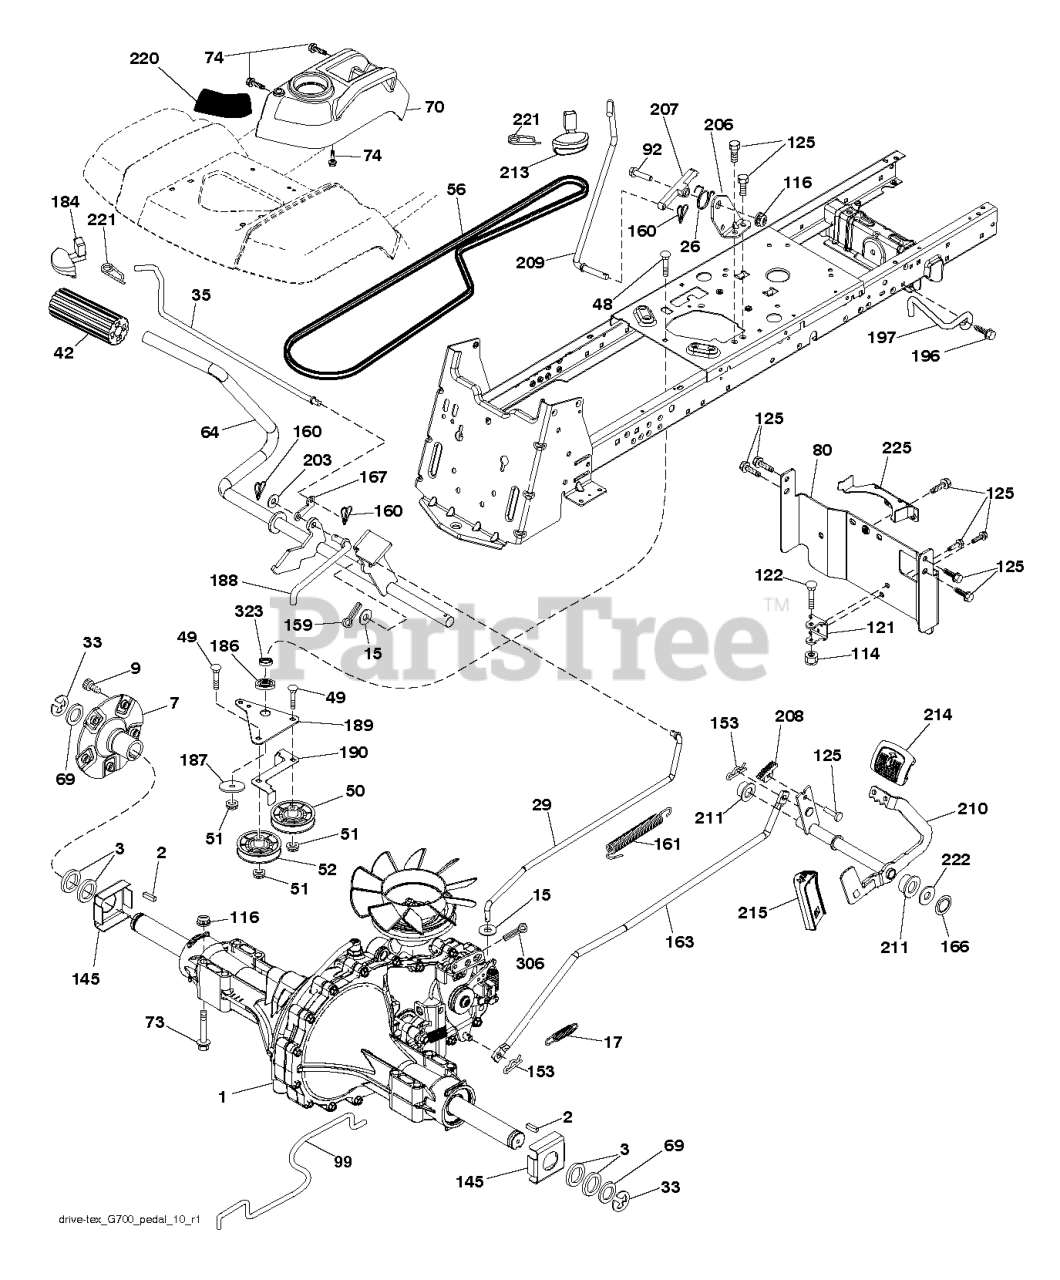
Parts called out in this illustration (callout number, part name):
2	KEY 1/4 X 2.5
7	HUB.ASM.WHEEL.REAR.23"TEX
9	HUB BOLT
15	WASHER
17	SPRING.BRAKE.K46
26	SPRING.RETURN.CRUISE
29	ROD.BRAKE.K66
33	E RING HYT
35	ROD .BRAKE. PARKING. GT. HUSQ.
42	PEDAL COVER T
48	BOLT.3/8-16X1.50
50	IDLER.FLAT.910.OFFSET
51	NUT LOCK FLG 3/8-16 UNC
52	IDLER.V-GROOVE.910.OFFSET
64	SHAFT.ASM.PEDAL.BRK.CNTR
70	CONSOLE.ASM.RH.GT.FC.HUSQ
73	BOLT HEX 5/16-18 GR 5
74	SCREW.HI-LO.CONSOLE
80	STRAP.TORQUE.K66
92	BOLT
99	ROD.SPRING.BYPASS.K66.GT.Z
114	NUT.71038.31-18.HEX.NYLOCK
116	NUT LOCK HEX FLANGE 5/16-18
121	BRACKET STRAP TORQUE
122	BOLT.5/16-18X2.5
125	SCREW
145	WASHER.AXLE.FLANGE.HG-3000
153	RETAINER M
159	COTTER PIN
160	RETAINER CLIP
161	SPRING, RETURN LT
163	ROD.PEDAL.CONTROL
166	NUT.PUSH.625
167	LATCH.BRAKE.SPRING
184	RB HANDLE.PARKG.BRK.HUS/PRED
186	BOLT.5/16-18X2.5
187	WASHER 12/32X2X10GA
188	RP.LINK.CLUTCH.GROUND.DRIVE
189	BELLCRANK.GROUND.DRIVE.TEX.
190	KEEPER.BELLCRANK.DRIVE
196	SCREW 3/8-16X1
197	BRKT.ANIT-ROTATION.CLUTCH
203	WASHER
206	BRACKET.MOUNT.CRUISE.LATCH
207	LATCH.CONTROL.CRUISE
208	GEAR.SECTOR.CONTROL.CR
209	ROD.CONTROL.CRUISE.GT.
210	ROCKER.ASM.PEDAL.CONTR
211	BEARING.NYLON
213	KNOB.CONTROL.CRUSIE.HU
214	PEDAL.FORWARD.PAD.TEX
215	PEDAL.REVERSE.TEX.GT.4
220	REFLECTOR.LH.TEX GT HU
221	RETAINER.SPRING.CLIP.H
222	WASHER 21/32 X 1-1/4 X 10 GA.
225	KEEPER.BELT.TRANSAXLE.K66
306	PIN COTTER
323	SLEEVE.BELLCRANK
